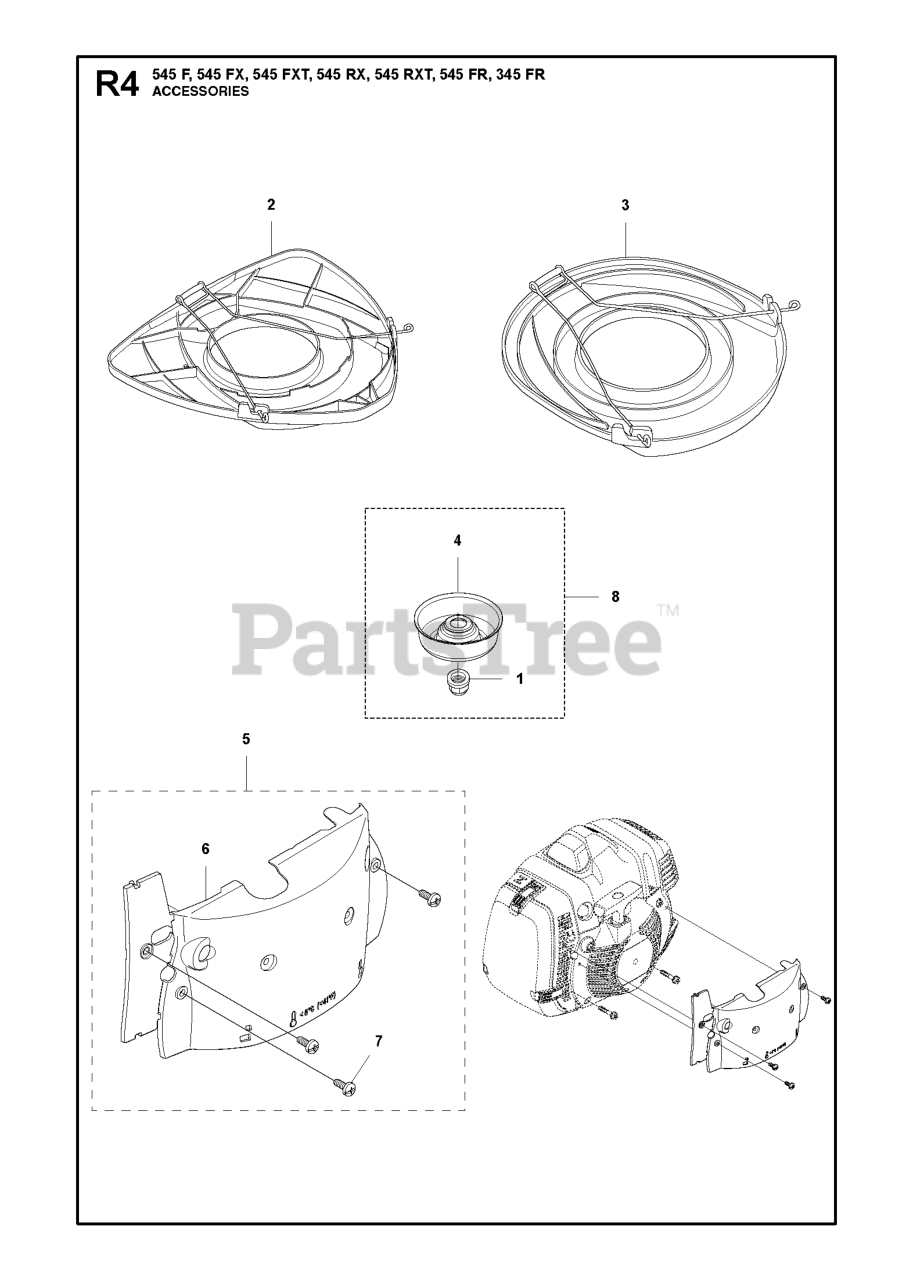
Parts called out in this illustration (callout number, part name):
2	TRANSPORT GUARD
3	BLADE GUARD TRANSPORT
4	SUPPORT CUP
5	WINTER KIT
6	WINTER COVER
